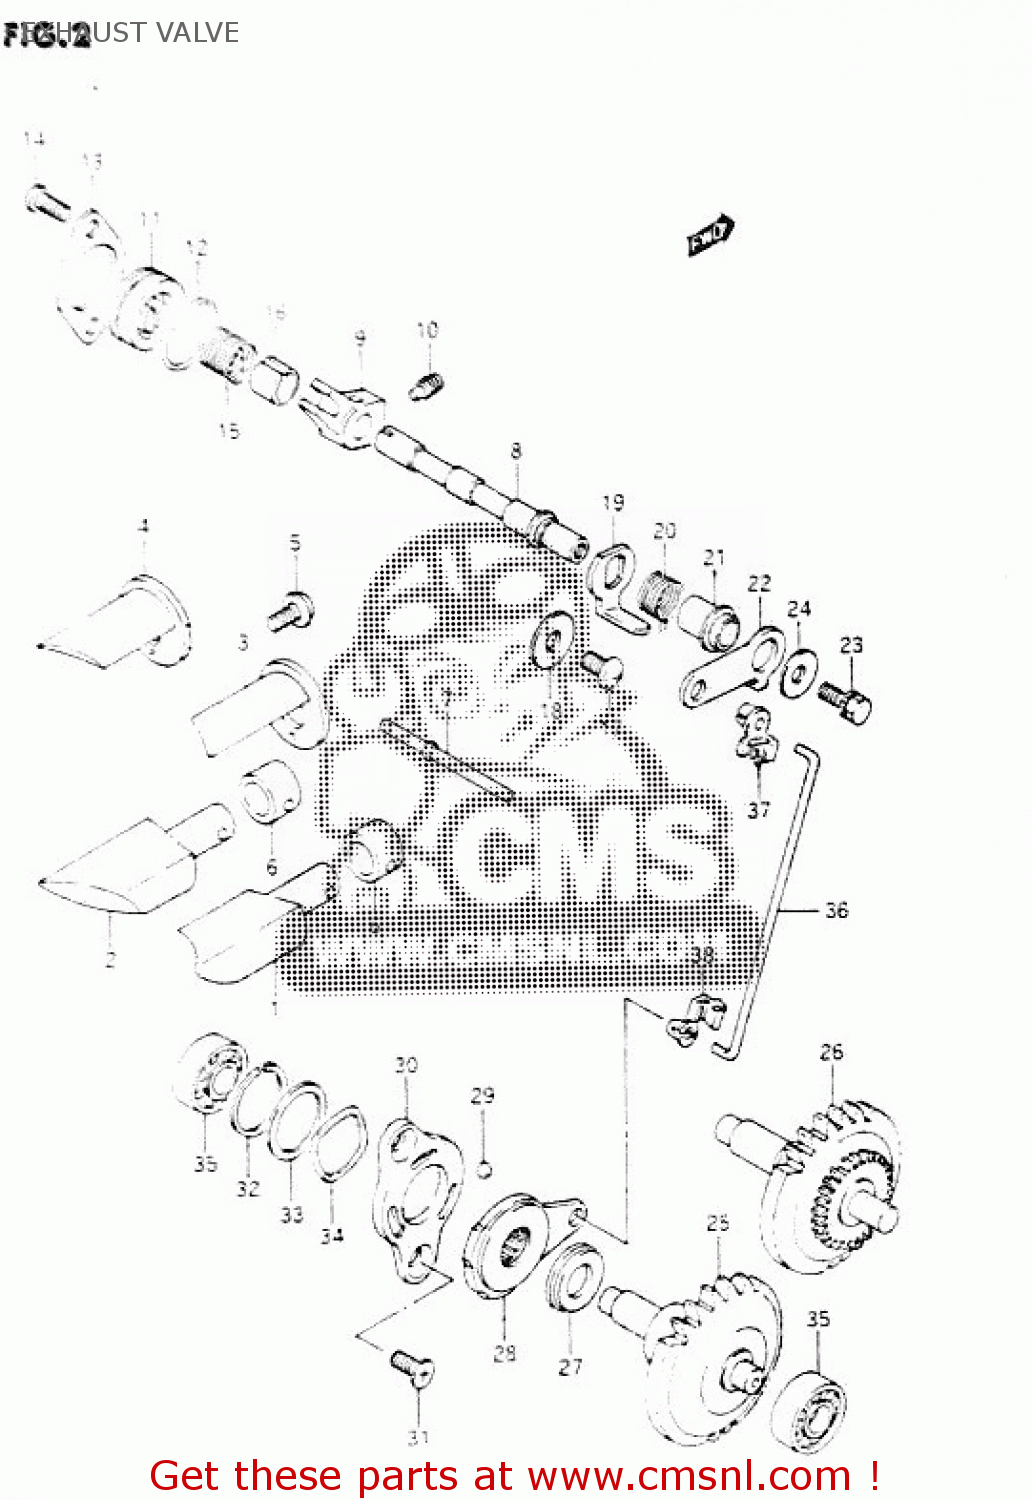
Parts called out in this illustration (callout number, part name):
1	VALVE,EXHAUST,R
2	VALVE,EXHAUST,L
3	GUIDE,EXHAUST VALVE,R
4	GUIDE,EXHAUST VALVE,L
5	SCREW
6	HOLDER,EXHAUST VALVE
7	PIN,EXHAUST VALVE 48.5MM
8	SHAFT,EXHAUST VALVE
9	ARM,EXHAUST VALVE SHAFT
10	SCREW
11	CAP,EXHAUST VALVE
12	O RING(D:1.9,ID:22.6)
13	RETAINER,EXHAUST VALVE
14	SCREW
15	SPRING
16	SPACER,EXHAUST VALVE SPRING
17	BOLT
18	WASHER
19	LEVER,EXHAUST VALVE NO
20	SPRING
21	SPACER,EXHAUST VALVE
22	LEVER,EXHAUST VALVE NO
23	BOLT
24	WASHER (5.5X16X1.2)
25	GOVERNOR ASSEMBLY,EXHAUST
26	GOVERNOR ASSY,EXHAUST VALVE
27	BEARING(10X22X2.8)
28	ACTUATOR,EXHAUST VALVE
29	BALL
30	STARTER,EXHAUST VALVE ACTUATOR
31	SCREW(5X10)
32	CIRCLIP
33	SHIM(19.1X25X0.3)
34	WASHER
35	BEARING(8X22X7)
36	ROD,EXHAUST VALVE
37	BUSH,EXHAUST VALVE ROD NO.1
38	BUSH,EXHAUST VALVE ROD NO.2
